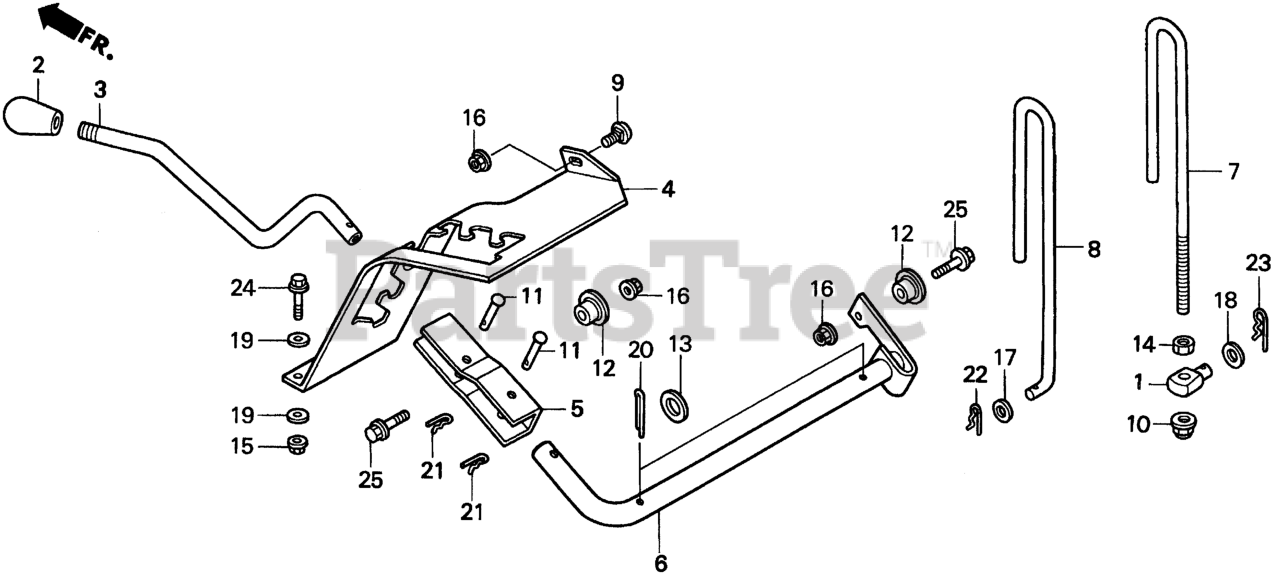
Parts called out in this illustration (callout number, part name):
1	PIN, LINK ADJUSTING
2	GRIP, HEIGHT ADJUSTING LEVER
3	LEVER, HEIGHT ADJUSTING
4	PLATE, RATCHET
5	BRACKET, HEIGHT ADJUSTING LEVER
7	BAR, R. ADJUSTING
8	BAR, L. ADJUSTING
9	BOLT, SPECIAL (9X15)
10	NUT, SELF-LOCK (OHASHI)
11	PIN, HEIGHT ADJUSTING
12	COLLAR, L. ARM
13	WASHER, PLAIN (26MM)
14	NUT, HEX. (12MM)
15	NUT, FLANGE (6MM)
16	NUT, FLANGE (8MM)
17	WASHER, PLAIN (12MM)
18	WASHER, PLAIN (14MM)
19	WASHER, PLAIN (6MM)
20	PIN, COTTER (5.0X40)
21	PIN, LOCK (8MM)
22	PIN, LOCK (12MM)
23	PIN, LOCK (14MM)
24	BOLT, FLANGE (6X35)
25	BOLT, FLANGE (8X30)
